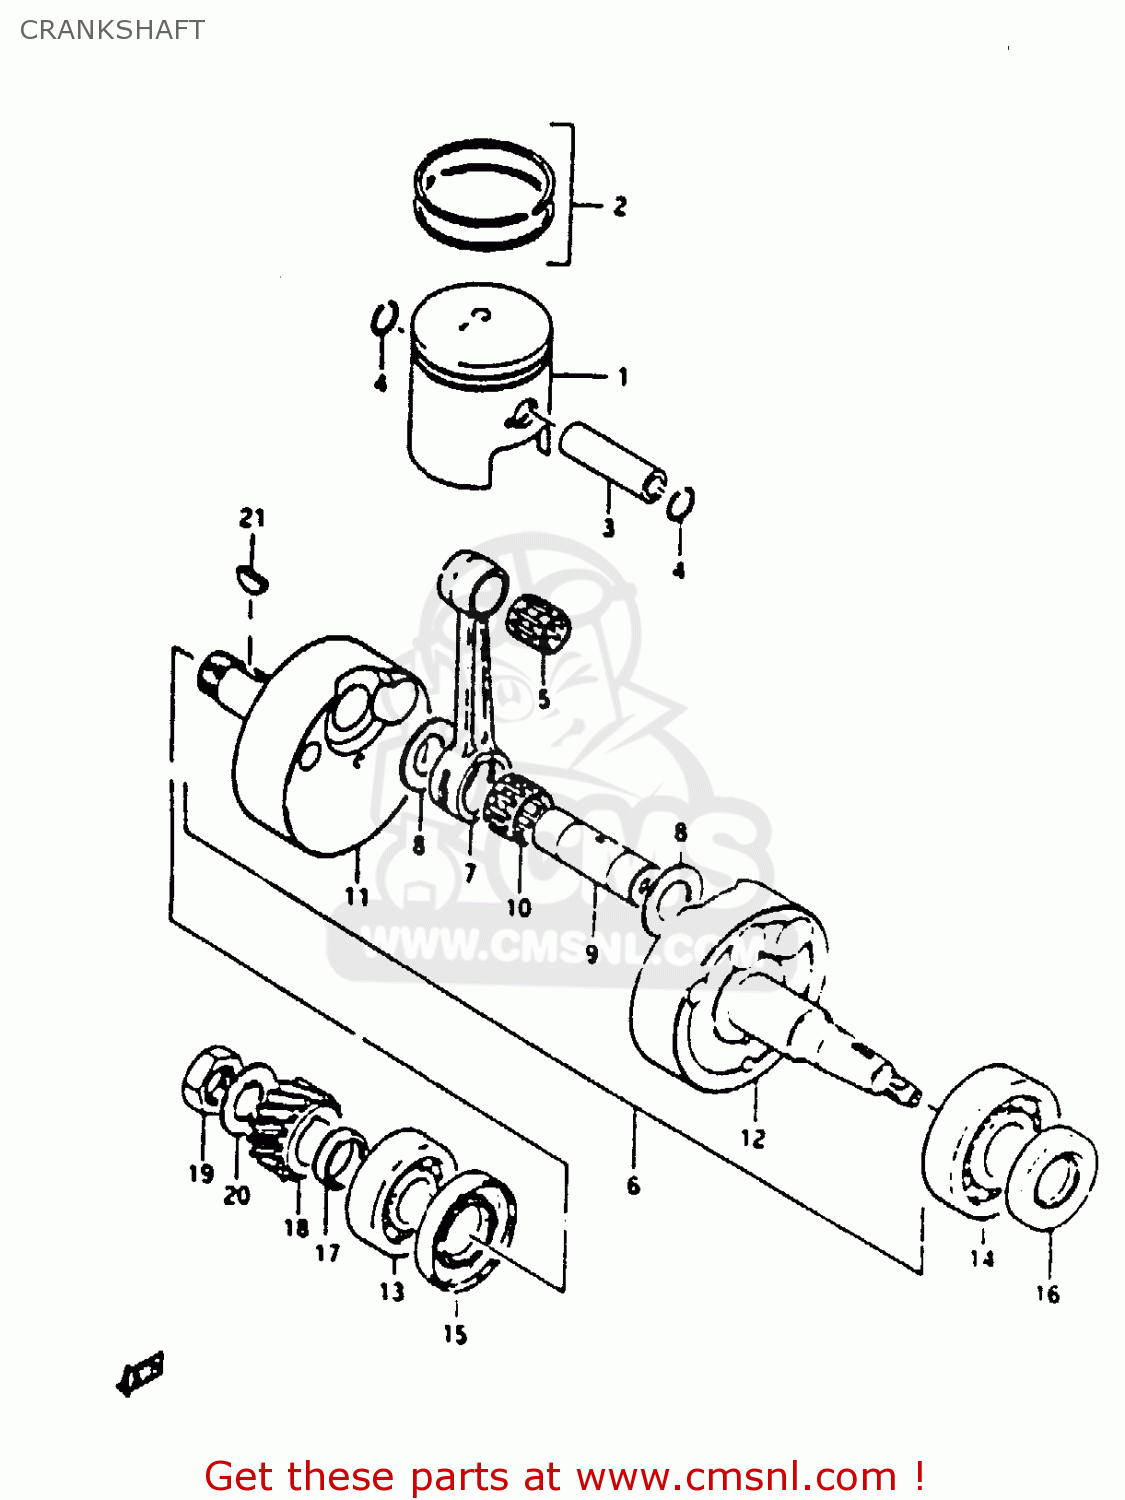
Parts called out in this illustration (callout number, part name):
1	PISTON
2	RING SET,PISTON
3	PIN,PISTON
4	RING,SNAP 14MM
5	BEARING
6	CRANKSHAFT ASSEMBLY
7	CONNECTING ROD
8	WASHER(19X32X1)
9	PIN,CRANK
10	BEARING(19X25X16)
11	CRANKSHAFT,R
12	CRANKSHAFT,LEFT
13	BEARING
14	BEARING(25X62X17)
15	SEAL,OIL(26X52X8)
16	OIL SEAL
17	SPACER(20X28X7)
18	GEAR,PRIMARY DRIVE
19	NUT
20	WASHER
21	KEY
